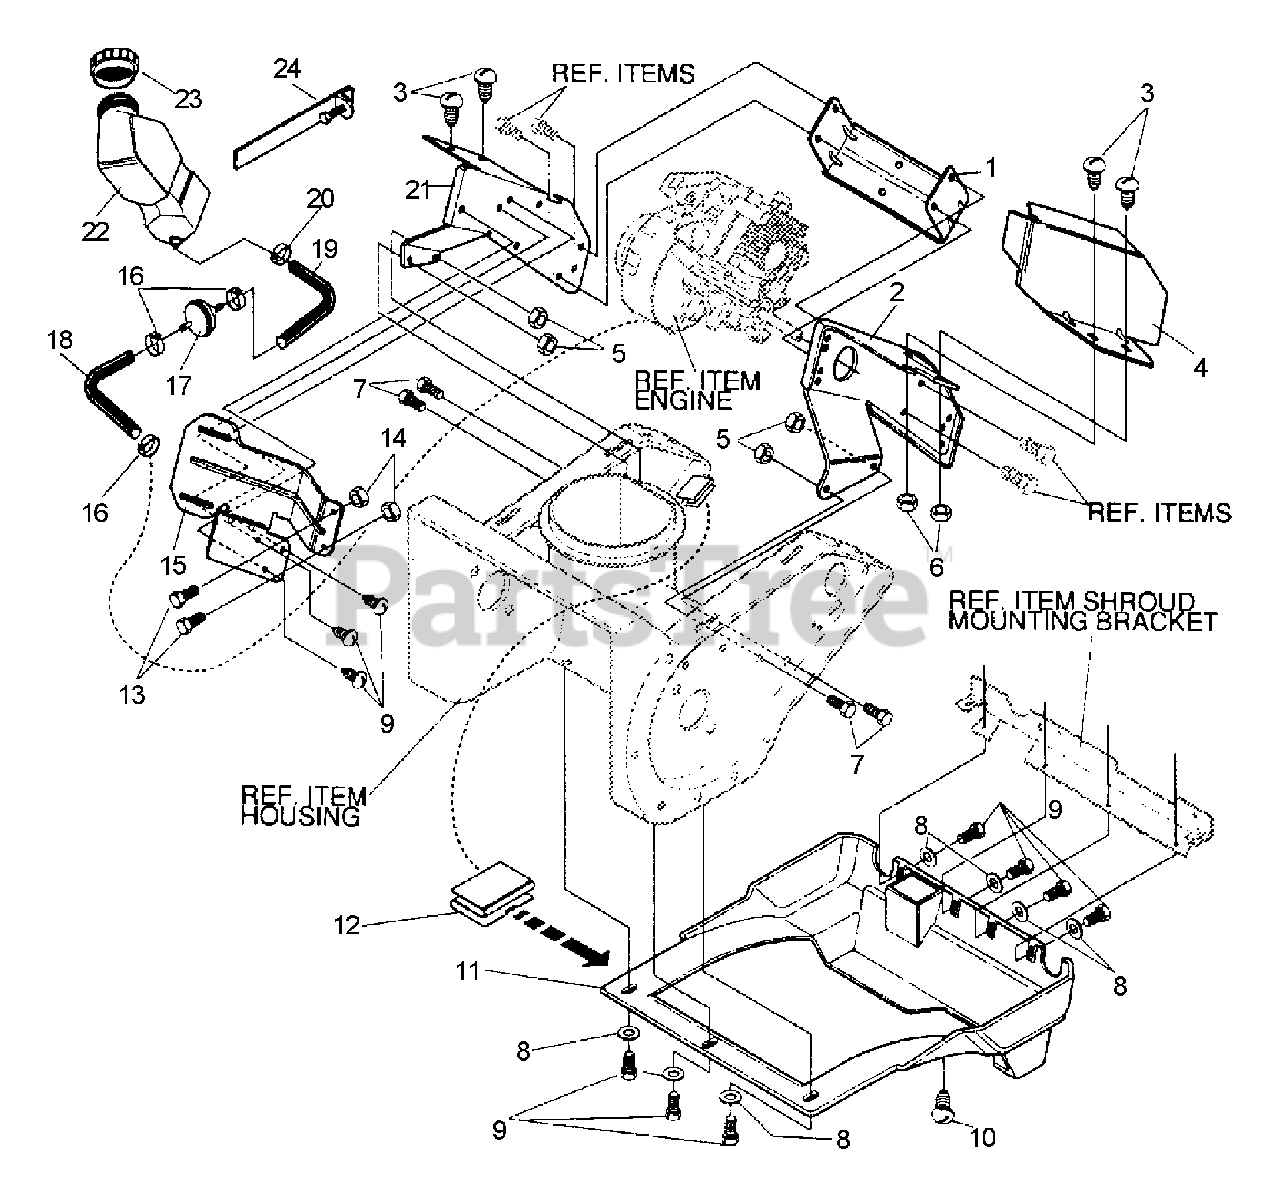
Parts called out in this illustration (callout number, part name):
1	SUPPORT, FRAME
2	PLATE, REAR MOUNT -- LEFT
3	SCREW - 1/4-20×0.63"
4	SHIELD, HEAT
5	NUT, 5/16"-18
6	NUT, 1/4"-20
7	SCREW - 5/16-18 X0.50" -- HEX HEAD CAP
8	WASHER
9	SCREW - 10-24×0.63" -- PAN HEAD
10	SCREW - 10-16×0.50"
11	SHROUD, BOTTOM
12	CLIP
13	SCREW - 10×24×0.50" -- HEX HEAD MACHINE
14	NUT
15	BRACKET, FUEL TANK
16	CLAMP, HOSE
17	FILTER
18	TUBING, GAS LINE 30"
19	TUBING, GAS LINE 8"
20	CLAMP, HOSE
21	PLATE, REAR MOUNT -- RIGHT
22	TANK, FUEL
23	CAP, FUEL
24	CLAMP, WORM DRIVE
